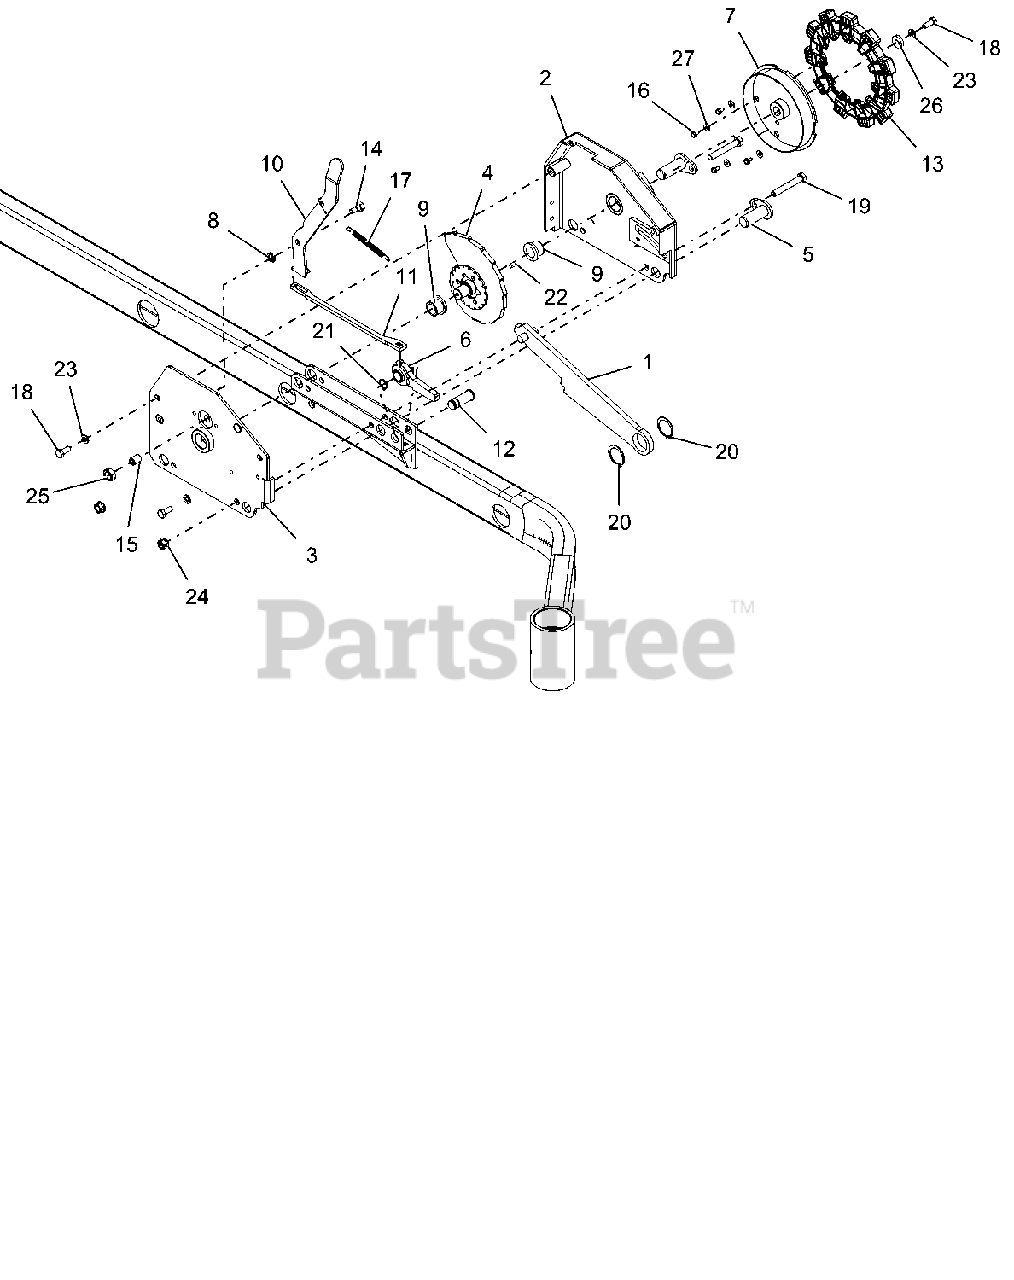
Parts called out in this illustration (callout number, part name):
1	WLDMT, HOC LINK-BLACK
2	WLDMT, HOC INNER-RED
3	WLDMT, HOC OUTER-RED
4	WLDMT, CAM HOC
5	WLDMT, PIN
6	WLDMT, LOCK PAWL
7	WLDMT, HOC WHEEL (RED)
8	WAVE WASHER .390X.655X.110
9	BUSHING, FLANGE
10	LEVER, TRANSPORT LOCK-BLACK
11	LINK, TRANSPORT LOCK-BLACK
12	PIN, CLEVIS .625 SNAP RING
13	WHEEL, HOC
14	BOLT, SHLDR .38-16 x .437 HEX YZ
15	BALL SPRING PLUNGER, .500-13
16	SCR, TAP 10-24X.375 PRE-COAT 80
17	SPRG, EXTENSION
18	BLT-HEX .31-18X.75 GR5 YWZC
19	BLT-HEX .38-16X2.50 GR5 YWZC
20	RG-RTNG-EXT 1.25x.050
21	RG-RTNG-EXT .625x.050
22	KEY-SQ .188X.188X.375
23	WSHR-LK .31X.078 REG YWZC
24	NUT, LK-CTR-FLG .38-16 YWZC
25	NUT, JAM .500-13 YWZC
26	WSHR-FL-STL .328X.87X.179 YWZC
27	WSHR-FL-STL.219X.500X.049YWZC
